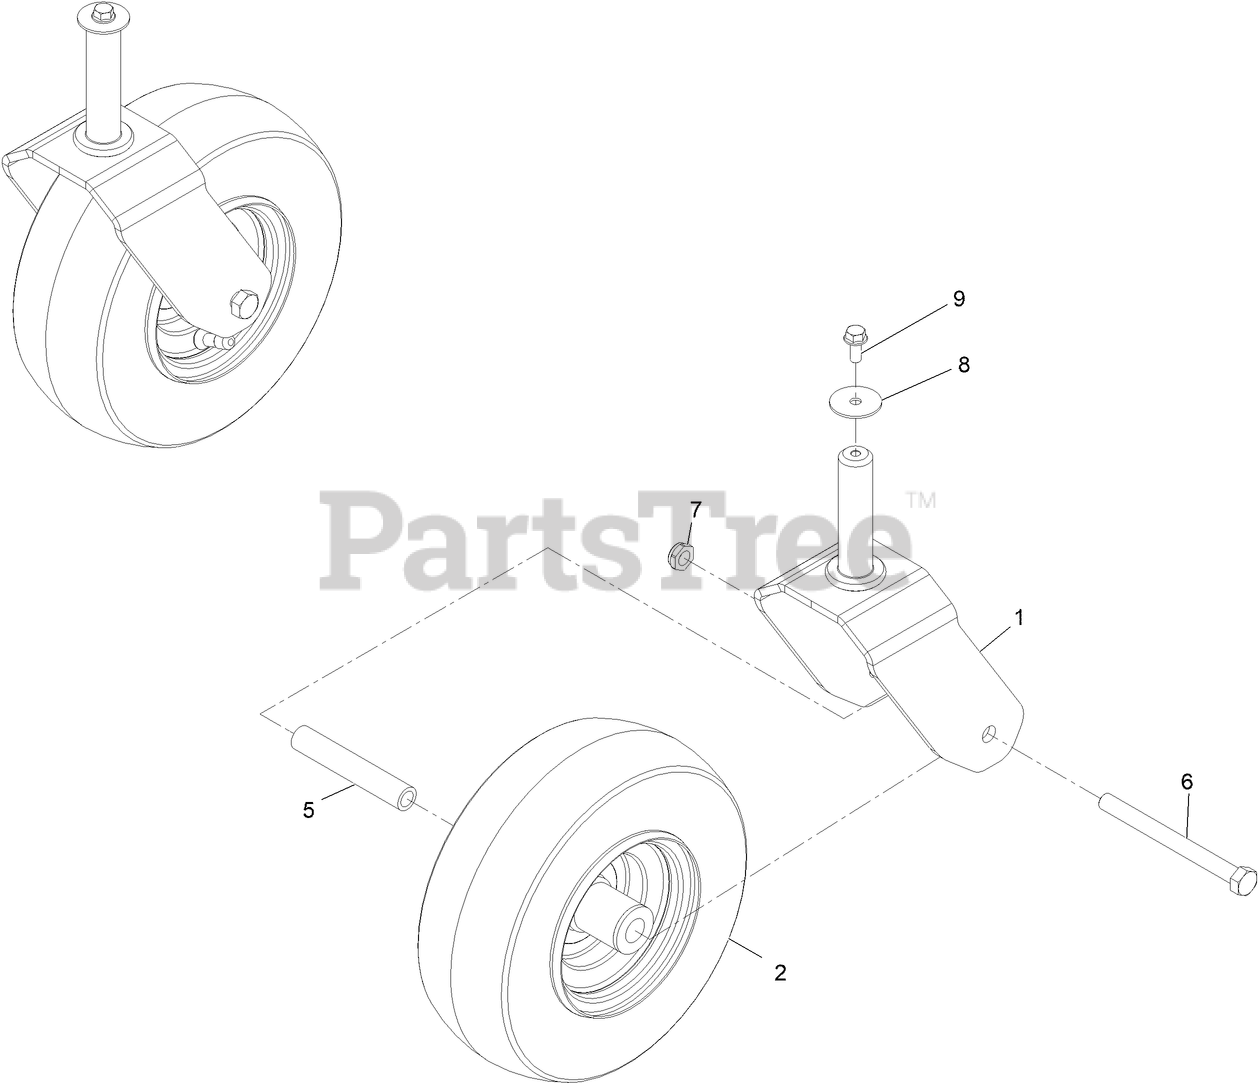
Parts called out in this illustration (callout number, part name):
2	TIRE ASM
5	BUSHING-SPANNER
6	SCREW-HH
7	NUT-HEX
8	WASHER-FLAT
9	SCREW-HHF
